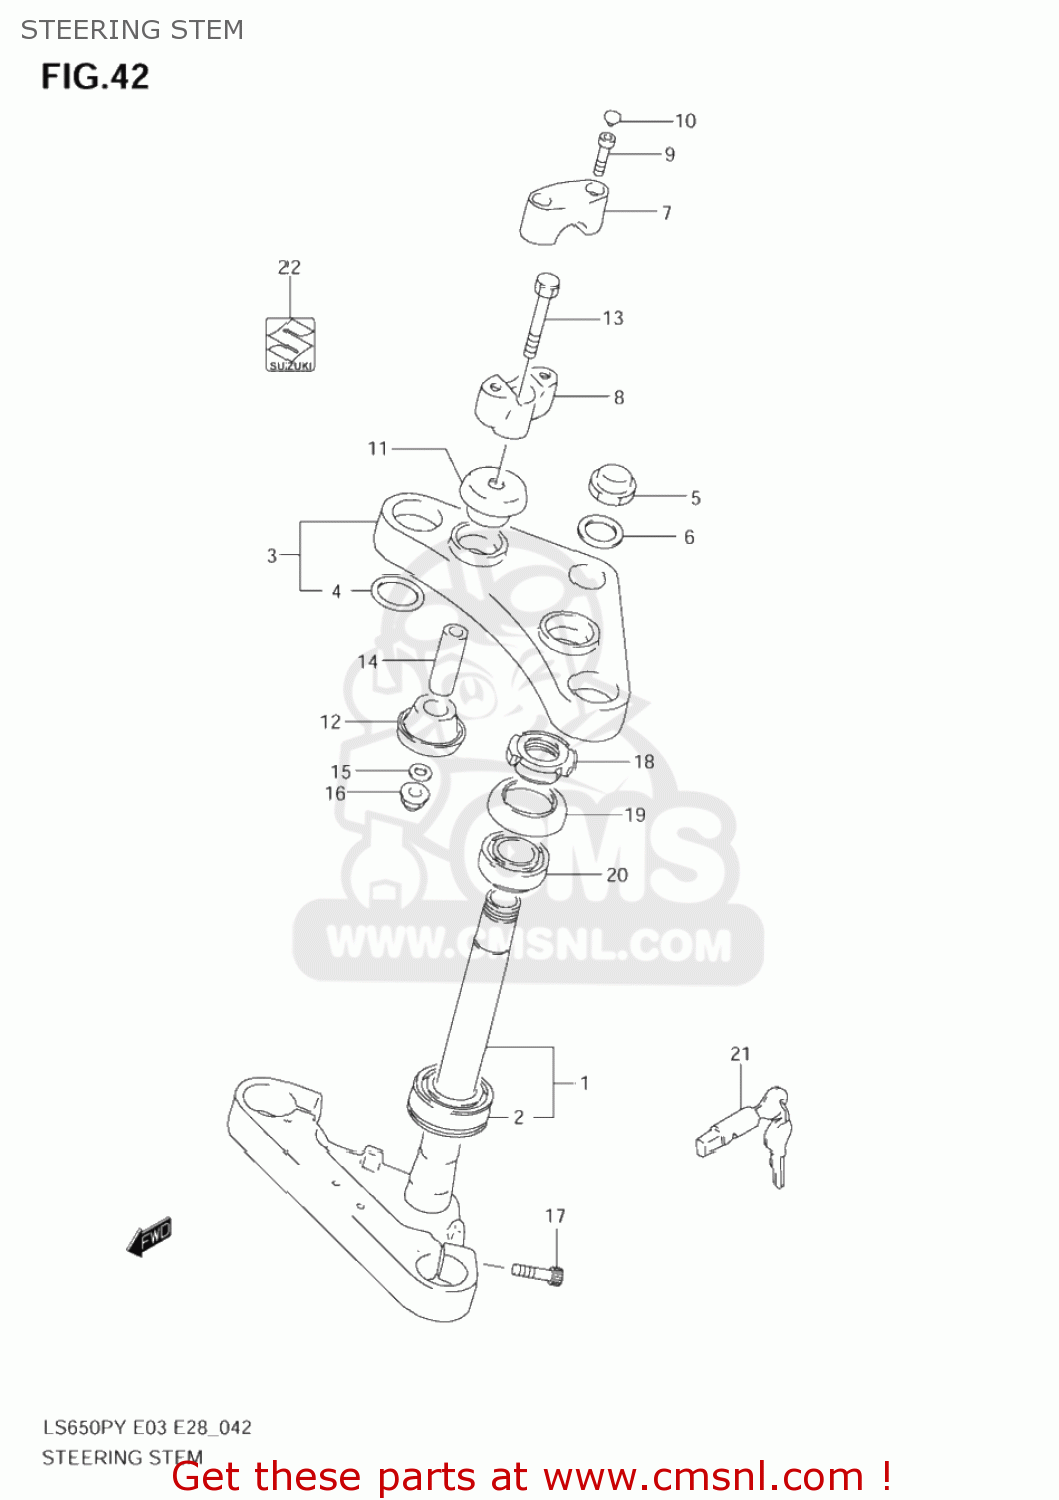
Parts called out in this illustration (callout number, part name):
1	STEM,STEERING
2	BEARING(30X55X17)
3	HEAD,STEERING STEM
4	WASHER,STEM HEAD,LOWER
5	NUT,CAP
6	WASHER(22.5X32X1.6)
7	HOLDER,HANDLE UPR
8	HOLDER,HANDLE LWR
9	BOLT
10	CAP(OD:14.5)
11	CUSHION,UPR
12	CUSHION,LWR
13	BOLT,DAMPER(10X77)
14	SPACER(10.2X14X46)
15	WASHER
16	NUT
17	BOLT
18	NUT,STEERING STEM(25X44X10)
19	SEAL,STEERING UPR DUST
20	BEARING(25X47X15)
21	LOCK ASSEMBLY,STEERING (NEI
22	EMBLEM,S
